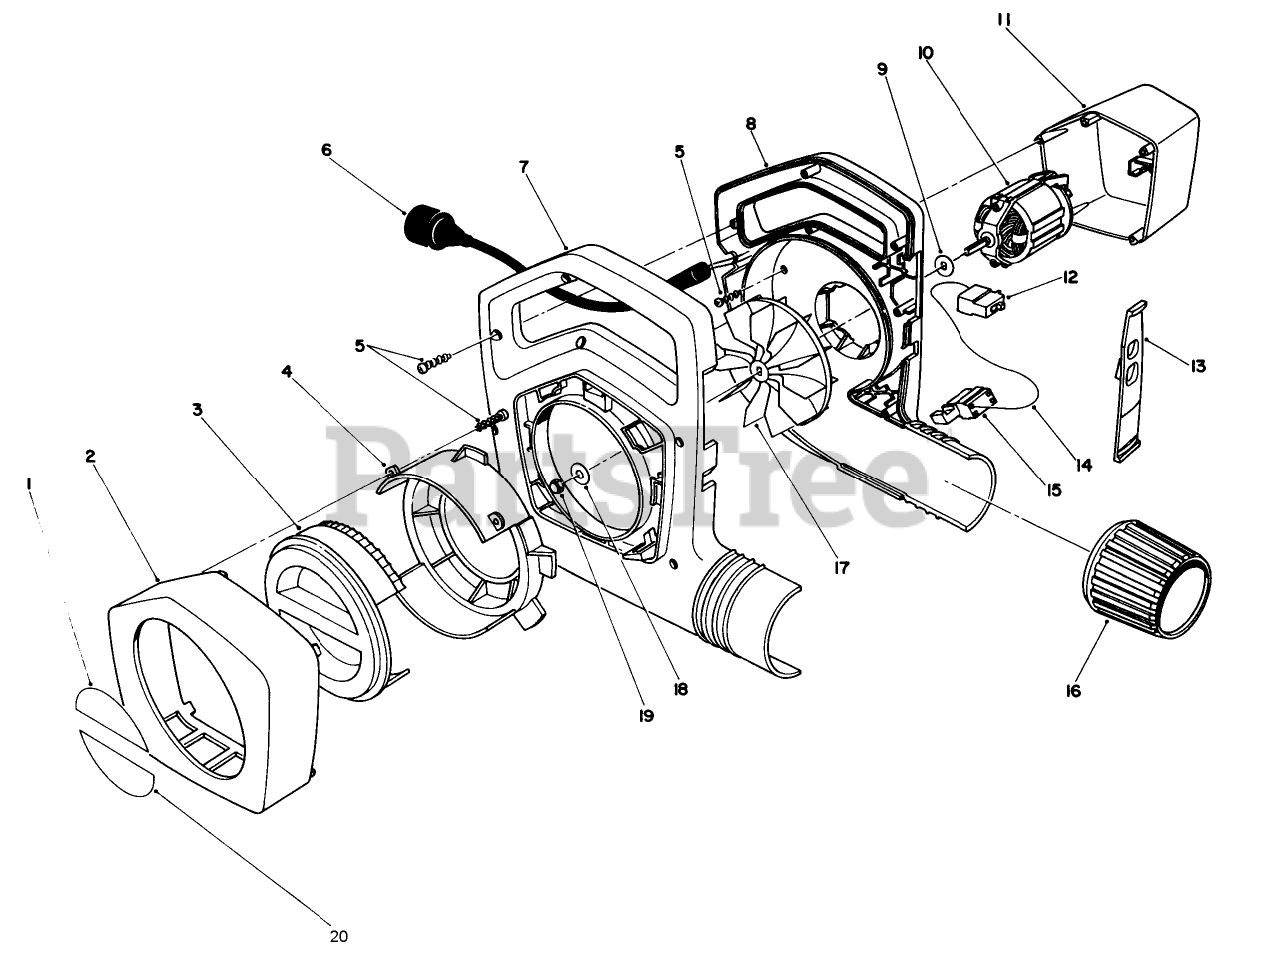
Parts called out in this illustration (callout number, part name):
1	Decal-Upper Choke (Model No. 51535)
2	Ring-Trim
3	Adjuster-Choke
4	Ring-Tab
5	Screw
6	Cord-Power Supply
7	Housing Assembly-R.H.
8	Housing-L.H.
9	Washer-Impeller
10	Motor
11	HOT STAMPED MOTOR COVER
12	Switch-On/Off
13	Cam-Switch-On/Off
14	WIRE -INTERNAL
15	SWITCH-INTERLOCK
16	Collar-Output
17	Impeller
18	WASHER-FLAT
19	NUT-LOCK, CAP
20	DECAL, LOWER CHOKE, 450
